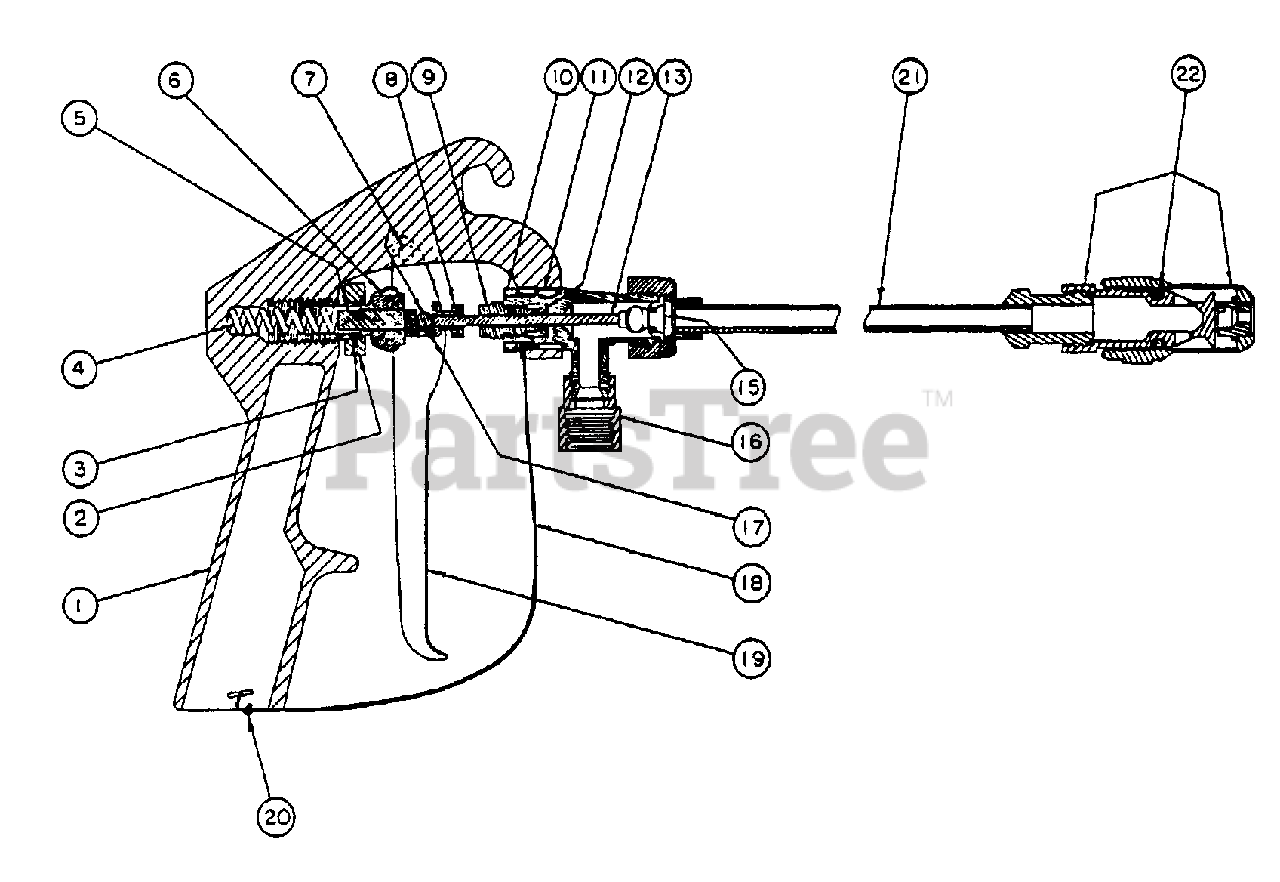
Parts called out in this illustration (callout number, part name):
1	Body Alum. 16054-I-AL
2	Safety Lock Cam 9422-AL
3	Socket Hd. Set Scw. 9423-L
4	Main Spring 16053-2-SS
5	Spring Stud 7591-ALEF
6	Safety Lock Scw. 9421-INP
7	Rivet 8038-ICP
8	Stem Nut 7484-INP
9	Packing Scw. 16071-NP
10	Lock Nut 7486-ICP
11	Key Steel 7892-ICP
12	Cup Packing 14255-I-BU
13	Main Stem ASB. 7482-I
15	Valve Seat 7490-CTEF
16	Inlet Body 16052-NP
17	Trigger Guide 7481-INP
18	Trigger Guard 9539-INP
19	Trigger 14252-INP
20	Pan Hd. Scw. 9697-INP
21	Brass Extension 4671-24
22	Adjustable Conejet 5780
